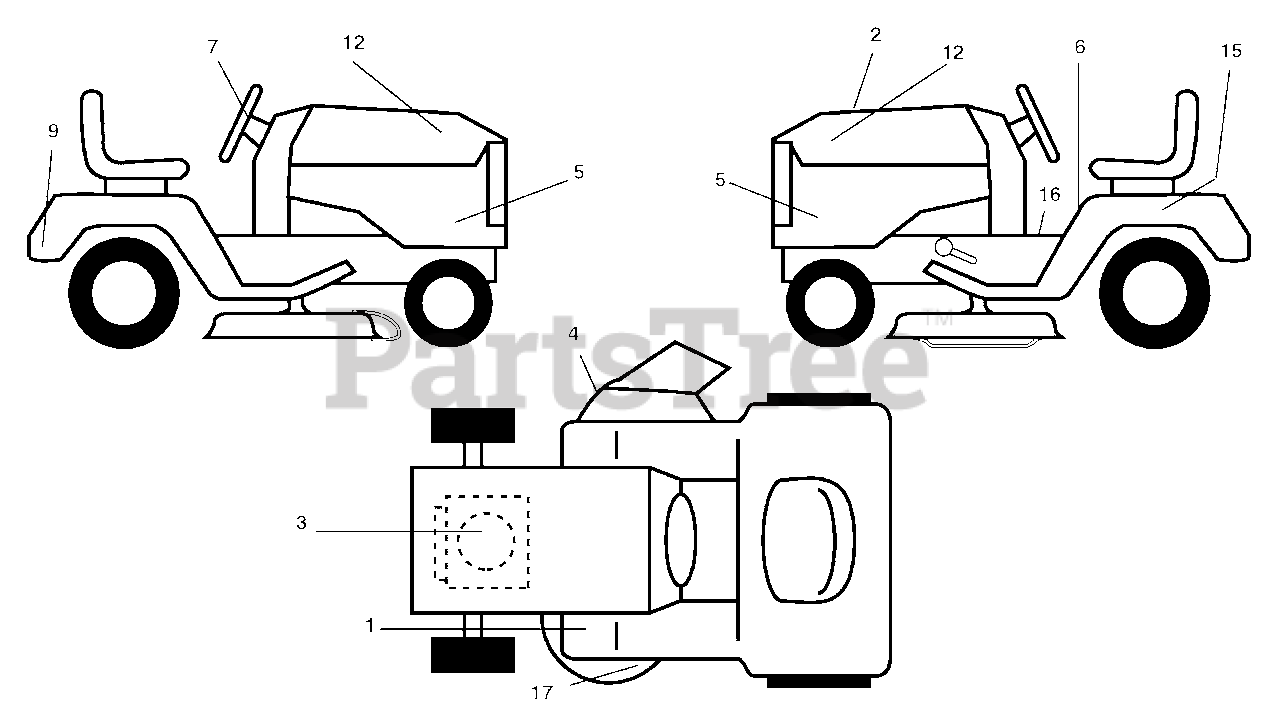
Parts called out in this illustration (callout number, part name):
1	Decal, Clutch Brake
2	Decal, Replacement
3	Decal, Engine HP
4	Decal Warning
5	Decal, Hood
6	Decal, Fender Danger English
7	Decal Ins Str Wh
9	Decal Fender
12	Decal, Hood
15	Decal, Caution, Battery
16	Decal, Oper Sdl P/L Gear Dr Eng
17	Decal, V-Belt Sch.
